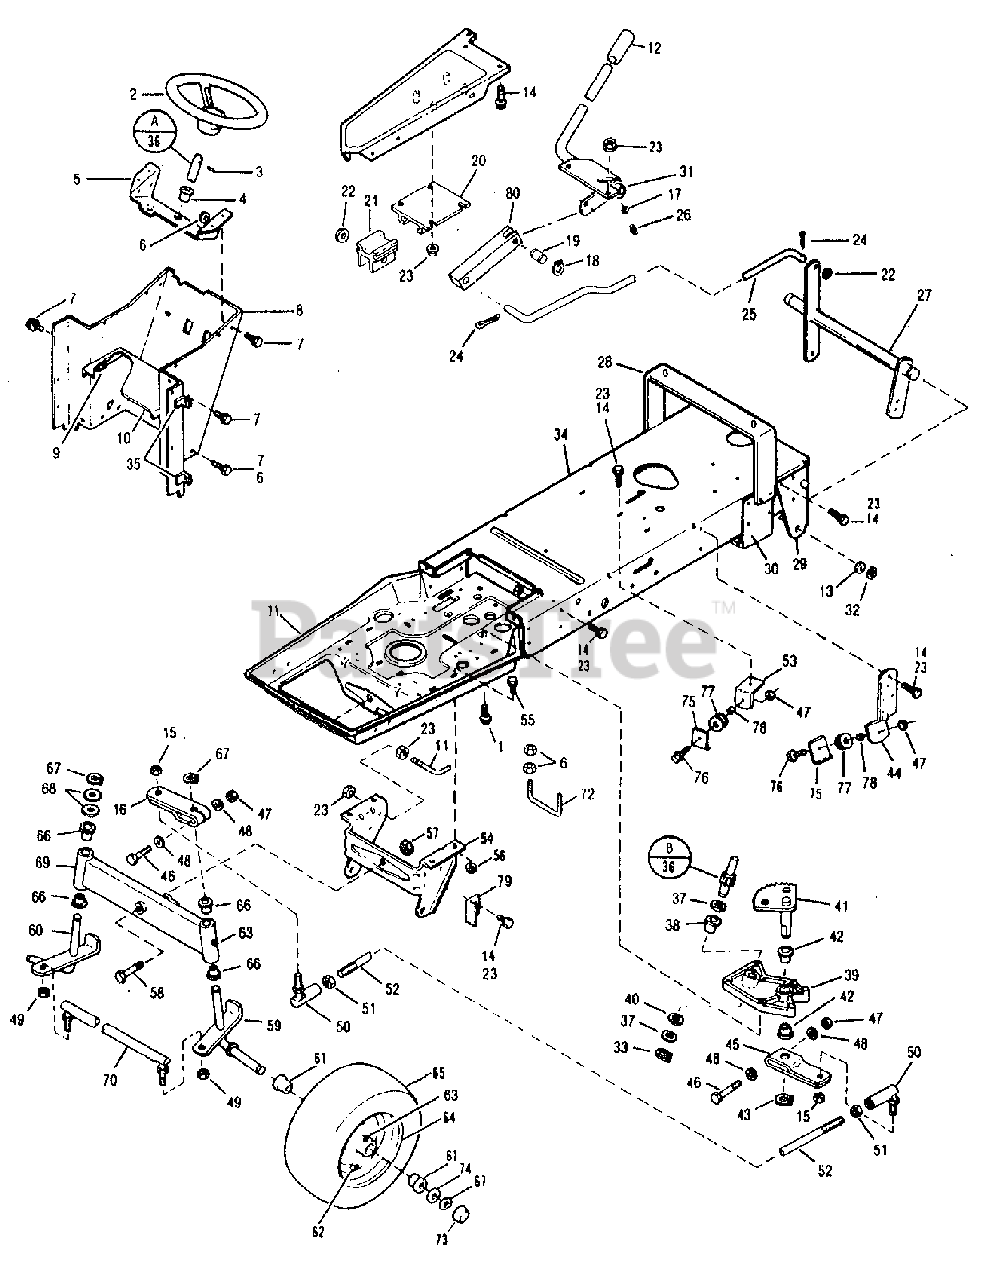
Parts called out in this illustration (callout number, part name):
1	Thread Forming Screw, 5/16-18x3/4
2	Steering Wheel
3	Roll Pin, 1/4x2-1/4
4	Flange Bearing
5	Steering Shaft Support
6	Flange Nut, 1/4-20
7	Flange Screw, 1/4-20x5/8
8	Instrument Panel Support
9	U-Type Speed Nut, 1/4-20
10	Battery Support
11	Belt Guide
12	Handle Grip
13	Flat Washer
14	Flange Lock Screw, 5/16-18x7/8
15	Jam Lock Nut, 1/2-20
16	Steering Arm
17	Washer
18	Retaining Ring
20	Stationary Guide (Incl. Ref. No. 21)
21	Sliding Guide (Incl. Ref. No. 20)
22	Flat Washer, 1/2"
23	Flange Lock Nut, 5/16-18
24	Cotter Pin, 1/8" x 1"
25	Lift Rod
26	Grease Fitting
27	Lift Shaft Assembly
28	Fender Support Assembly
29	Rear Panel Assembly
30	Axle Support
31	Lift Lever Assembly
32	Retaining Ring
33	Retaining Ring
35	Angle Bracket Speed Nut
36	Steering Shaft
37	Shim Washer
38	Flange Bearing
39	Steering Support Assembly
40	Thrust Washer
41	Sector Gear Assembly
42	Flange Bearing
43	Retaining Ring
44	Bracket
45	Spindle Arm Assembly
46	Hex Head Screw, 3/8-16 x 2-1/4
47	Hex Lock Nut, 3/8-16
48	Flat Washer, 3/8"
49	Lock Nut, 3/8-24
50	Ball Joint
51	Jam Hex Nut, 1/2-20
52	Steering Rod
53	Bracket
54	Attachment Bracket
55	Flange Hex Screw, 3/8-16 x 3/4
56	Flange Hex Nut,3/8-16
57	Hex Lock Nut, 5/8-11
58	Hex Head Screw, 5/8-11 x 2-1/2 (Grade 5 )
59	Spindle Assembly, LH
60	Spindle Assembly, RH
61	Flange Bearing
62	Valve Stem
63	Grease Fitting
64	Wheel (Incl. Refs. 61 & 63)
65	Tire, 15 x 6.00-6
66	Flange Bearing
67	Retaining Ring
69	Front Axle Assembly
70	Tie Rod
71	Front Frame
72	Belt Guide
73	Wheel Cap
74	Special Washer
75	Cable Guide
76	Hex Screw, 3/8-16 x 1-1/4
77	Pulley
79	Bracket
80	Push Link
